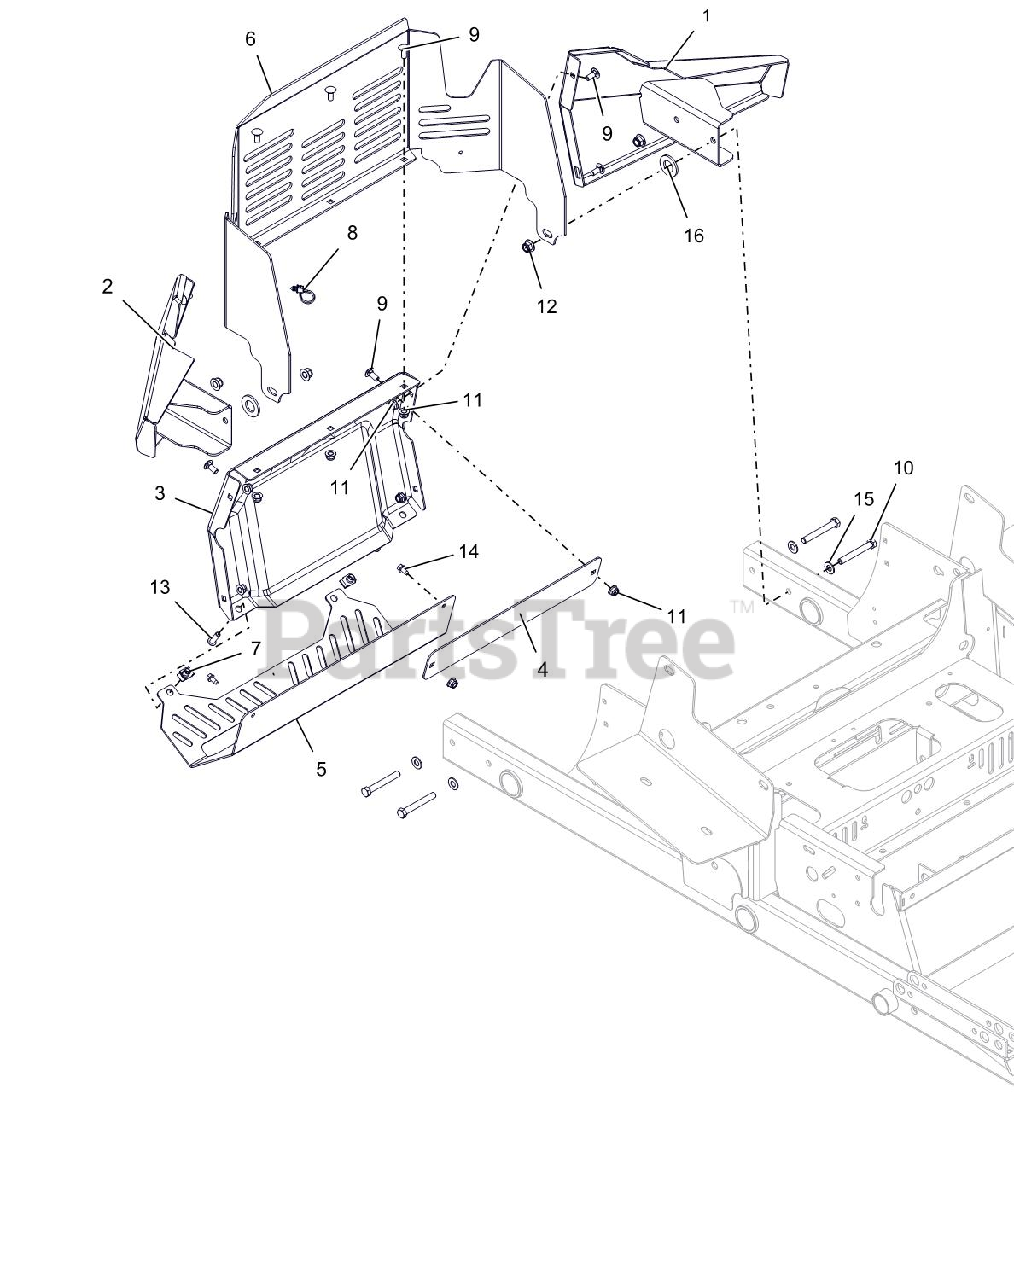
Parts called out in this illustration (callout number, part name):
1	WMT,LH REAR BMPR WING W/DECAL
2	WMT,RH REAR BMPR WING W/DECAL
3	PT200/400 REAR BUMPER - BLACK
4	BACKER PLATE - RED
5	PT200/400 MUFFLER GUARD - BLK
6	PT200 ENGINE GUARD - RED
7	NUT-CLIP RETAINER 5/16-18X.56
8	CABLE TIE W/ TREE (.25 HOLE)
9	@BLT-RDHDSQNK .31-18X.75 G5YZ
10	@BLT-HEX .38-16X2.75 GR5 YWZC
11	@NUT-LK-NYL-FLG .31-18 YWZC
12	@NUT-LK-NYL-FLG .38-16 YWZC
13	SCR-SKH .31-18X1.0 BTNHD YWZC
14	SCR-TAP .25-20X.50 HWH TR YWZ
15	@WSHR-FL-STL.406X.812X.065 YWZ
16	@WSHR-FL-STL.812X1.50X.135YWZC
